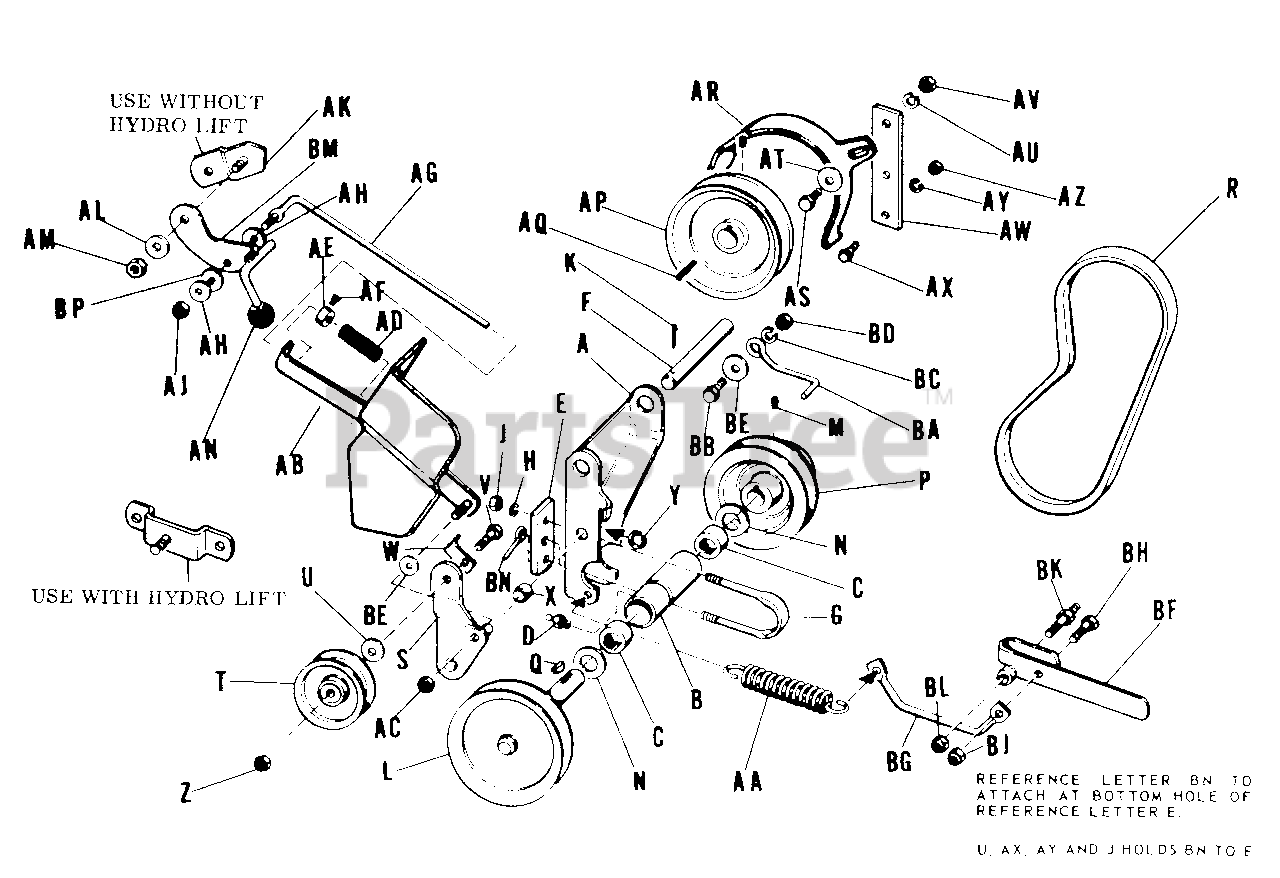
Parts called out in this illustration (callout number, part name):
A	P.T.O. - Bracket
B	Bearing Housing
C	Needle Bearing
D	Grease Fitting
E	Support Plate
F	Pivot Rod, 5/8" Dia. x 6-13/16"
H	Lock Washer, 5/16"
J	Full Hex. Nut, 5/16"-18
K	Cotter Pin, 3/16" Dia. x 1-1/2"
L	Shaft Assembly P.T.O
M	Set Screw 5/16"-18 x 5/16"
P	P.T.O. Pulley
Q	Woddruff Key #9-3/16" x 3/4"
S	Idler Lever Assembly
T	Idler Pulley
U	Plain Washer, 5/16"
V	Hex. Cap Screw 3/8"-16x 1-1/4"
Y	Retaining Ring
Z	Full Lock Hex. Nut, 3/8"-16
AA	Tension Spring
AB	Rod Guide Assembly
AC	Full Lock Hex. Nut, 3/8"-16
AF	Set Screw, 1/4"-20" x 3/8"
AG	Clutch Rod Assembly
AH	Plain Washer, 5/16"
AJ	Full Lock Hex. Nut, x 5/16"-18
AK	Pivot Bar Assembly
AL	Plain Washer 3/8"
AM	Full Lock Hex. Nut, 3/8"-16
AR	Belt Guard Assembly
AS	Hex. Cap Screw, 3/8"-16 x 1"
AT	Plain Washer, 5/16"
AU	Lock Washer, 3/8"
AV	Full Hex. Nut, 3/8"-16
AW	Belt Guard Support
AX	Hex. Capscrew, 5/16"-18 x 1"
AY	Lock Washer, 5/16"
AZ	Full Hex. Nut, 5/16"-18
BA	Belt Stop
BB	Hex. Cap Screw, 3/8"-16 x 7/8"
BC	Lock Washer, 3/8"
BD	Full Hex. Nut, 3/8"-16
BE	Plain Washer, 3/8"
BF	Handle Assembly
BG	Spring Tension Rod
BH	Hex. Capscrew, 5/16"-18 x 1-1/4"
BJ	Full Lock Hex. Nut,5/16"-18
BL	Full Lock Hex. Nut, 7/16"-14
BM	Clutch Lever Assembly
BN	Belt Guide
BP	Special Washer
